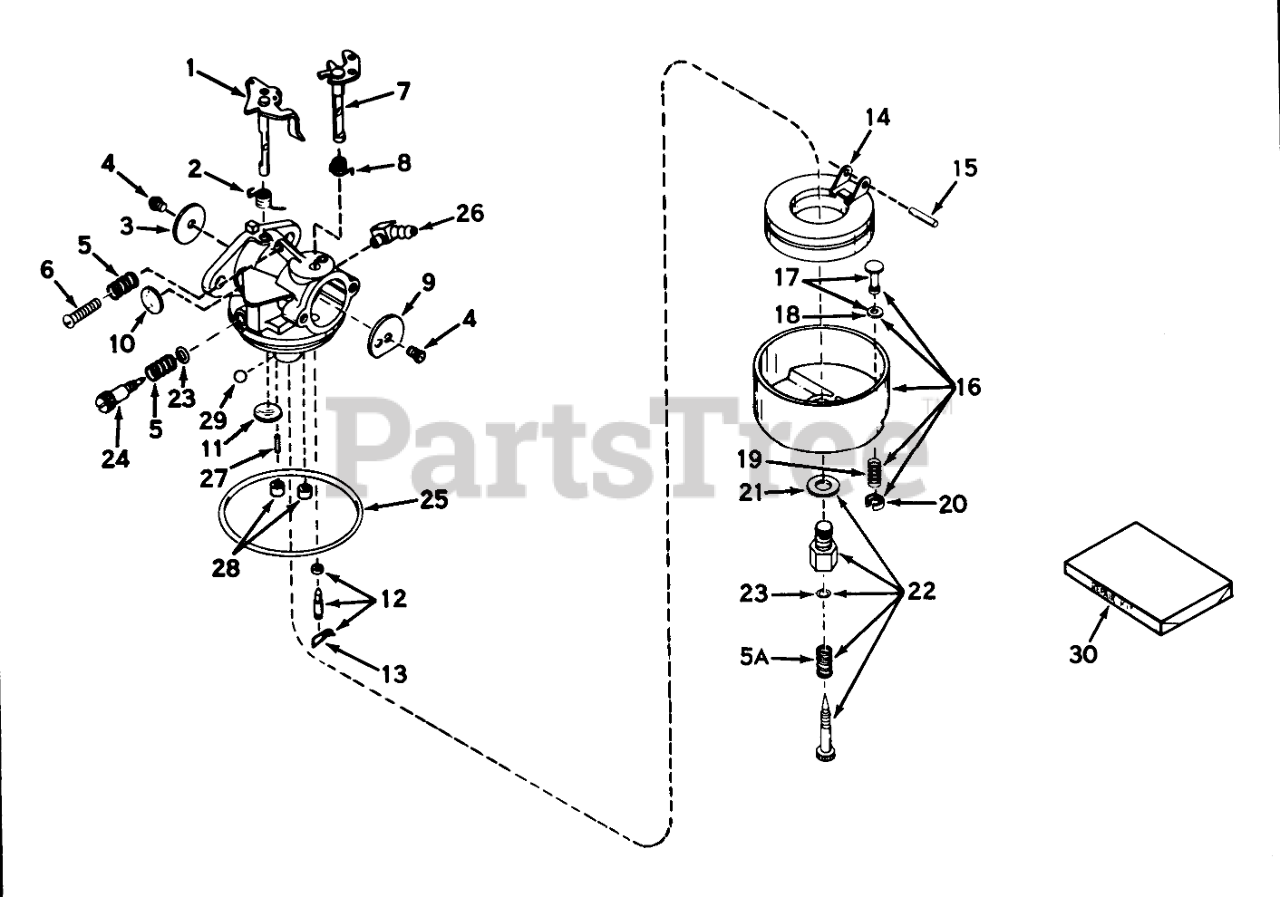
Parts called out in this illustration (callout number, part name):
1	Shaft & Lever Assy., Throttle
2	Spring, Return
3	Shutter, Throttle
4	Screw-Shutter
5	Spring-Tension
6	Screw-Throttle Crack Screw / Idle Speed
7	Shaft& Lever Assy., Choke
8	Spring, Choke return
9	Shutter-Choke
10	Plug-Welch, Idle Mixture Well
11	Plug-Welch, Atmospheric Vent
12	Inlet Needle, Seat & Clip Assy. (Incl. No.13)
13	Clip-Spring
14	Float,Carburetor
15	Shaft-Float
16	Bowl & Drain Assy. (Incl. Nos. 17 thru 20)
17	Plunger Assy., Drain (Incl. Ref. No.18)
18	Gasket-Plunger, Drain
19	Spring, Drain Plunger
20	Retainer, Plunger Spring
21	Washer-Bowl Nut
22	Adjustment Screw Assy., Main (Incl. Nos.5A,21 & 23)
23	"O"Ring
24	Screw, Idle Adj.
25	O Ring-Bowl, Float
26	Fitting Fuel Inlet
28	Plug, Cup
29	BalI, Steel
30	Repair Kit
